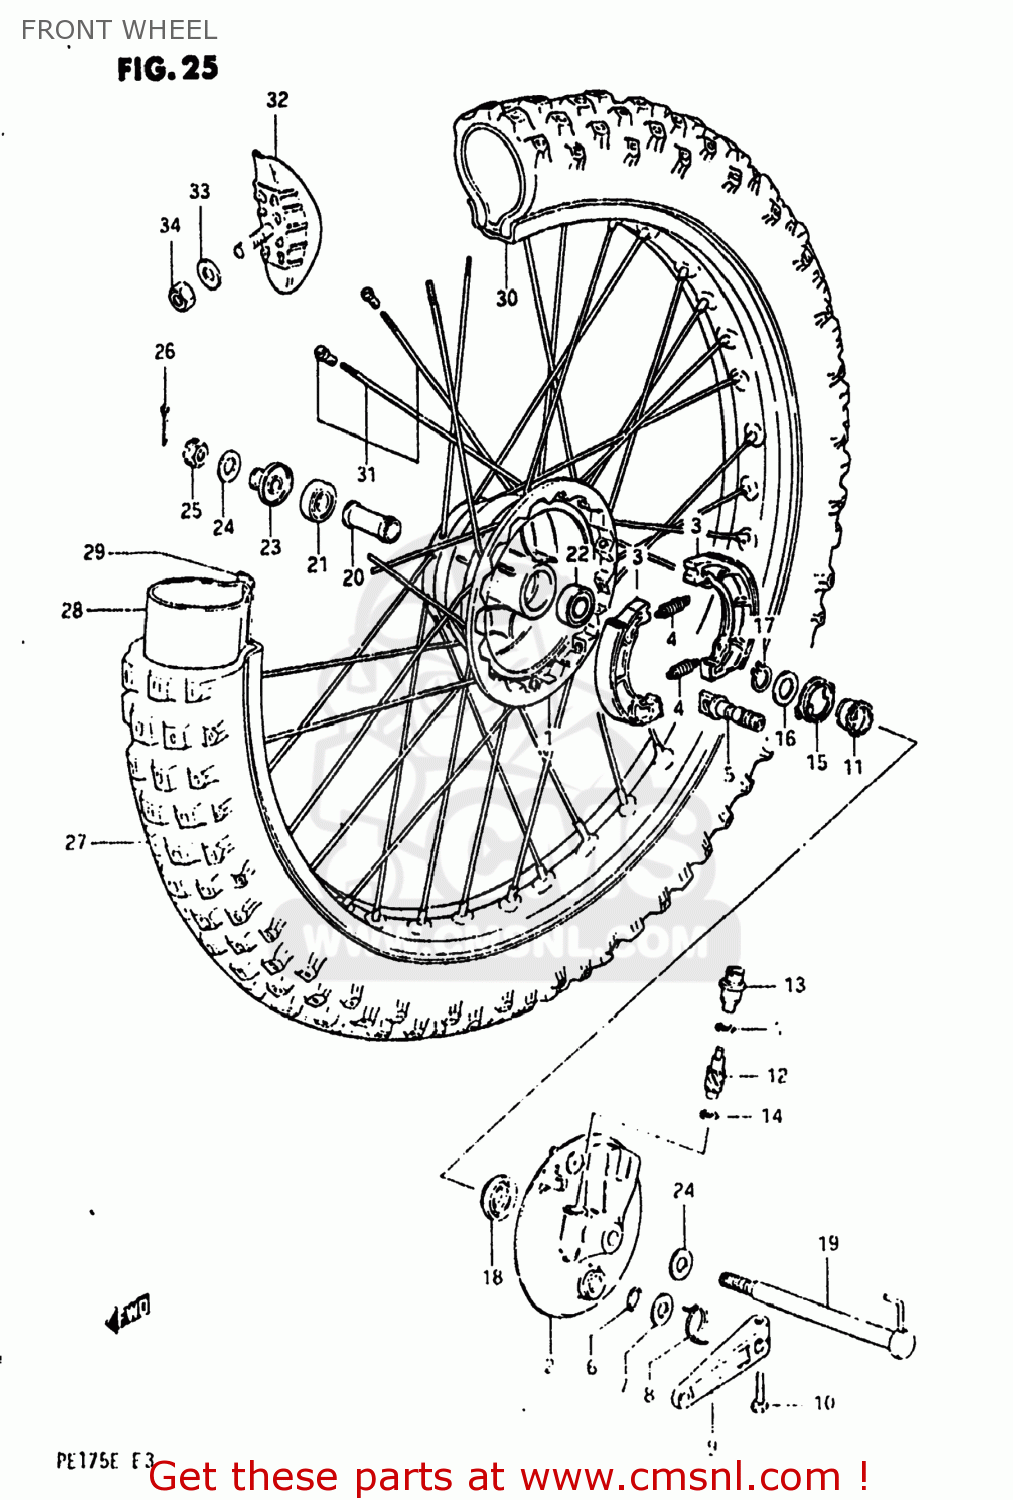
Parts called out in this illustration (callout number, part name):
1	HUB,FRONT
2	PANEL,FRONT HUB
3	SHOE,BRAKE (ASB)
4	SPRING
5	CAM,FR BRAKE
6	O RING(D:1.6,ID:12)
7	WASHER(12.5X20X1)
8	SPRING
9	LEVER,FRONT BRAKE CAM
10	BOLT
11	GEAR,SPEEDOMETER
12	PINION,SPEEDOMETER
13	BUSH,SPEEDOMETER PINION OUTER
14	WASHER (5.1X9X0.4)
15	DRIVER,SPEEDOMETER GEAR
16	WASHER(22.5X27X1)
17	CIRCLIP
18	SEAL,OIL(26X38X4)
19	AXLE,FRONT
20	SPACER,FRONT HUB BEARING
21	BEARING
22	BEARING
23	SPACER,FRONT AXLE,RIGHT
24	WASHER
25	NUT, REAR AXLE
26	COTTER PIN
27	TIRE,FRONT
28	TUBE
29	PROTECTOR,WHEEL,INNER
30	RIM,FRONT WHEEL
31	SPOKE SET,FRONT
32	STOPPER,BEAD
33	WASHER
34	NUT 8MM
